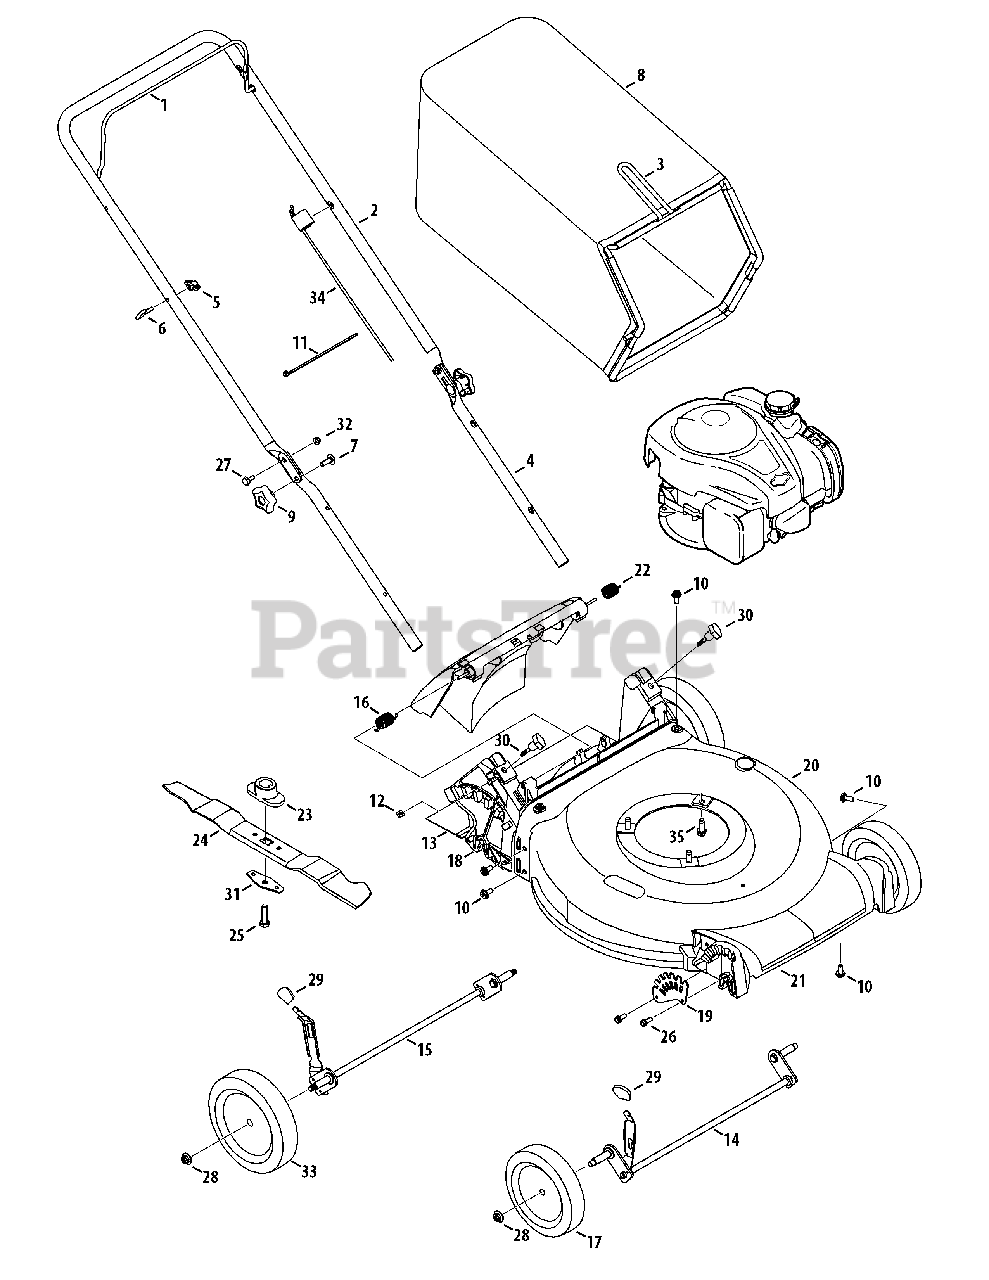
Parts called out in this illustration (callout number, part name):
1	Blade Control
2	Upper Handle
4	Lower Handle
5	Wing Nut
6	Rope Guide
7	Carriage Screw ,5/16-18
8	Grass Bag
9	Hand Knob
10	Screw, 5/16-14 x .750
11	Cable Tie
12	Nut, Sq., 1/4-20
13	Trail shield
14	Front Axle Assembly
15	Rear Axle Assembly
16	Torsion Spring - RH
17	Wheel, 7 x 1.8
18	Rear Discharge Assembly
19	Front Height Adjuster Plate
20	Deck - 21"
21	Front Cover
22	Torsion Spring - LH
23	Blade Adapter
24	Mulching Blade
25	Screw, 3/8-24 x 1.50
26	Screw, 1/4-15 x .750
27	Sldr. Screw, .375 x .126 x 1/4-20
28	Flange Lock Nut, 3/8-16
29	Adjustment Lever Knob
30	Wing Knob
31	Blade Bell Support
32	Nut, Flange Lock, 1/4-20
33	Wheel, 8 x 1.8
34	Control Cable
35	TT Sems Screw, 3/8-16 x 1.0
